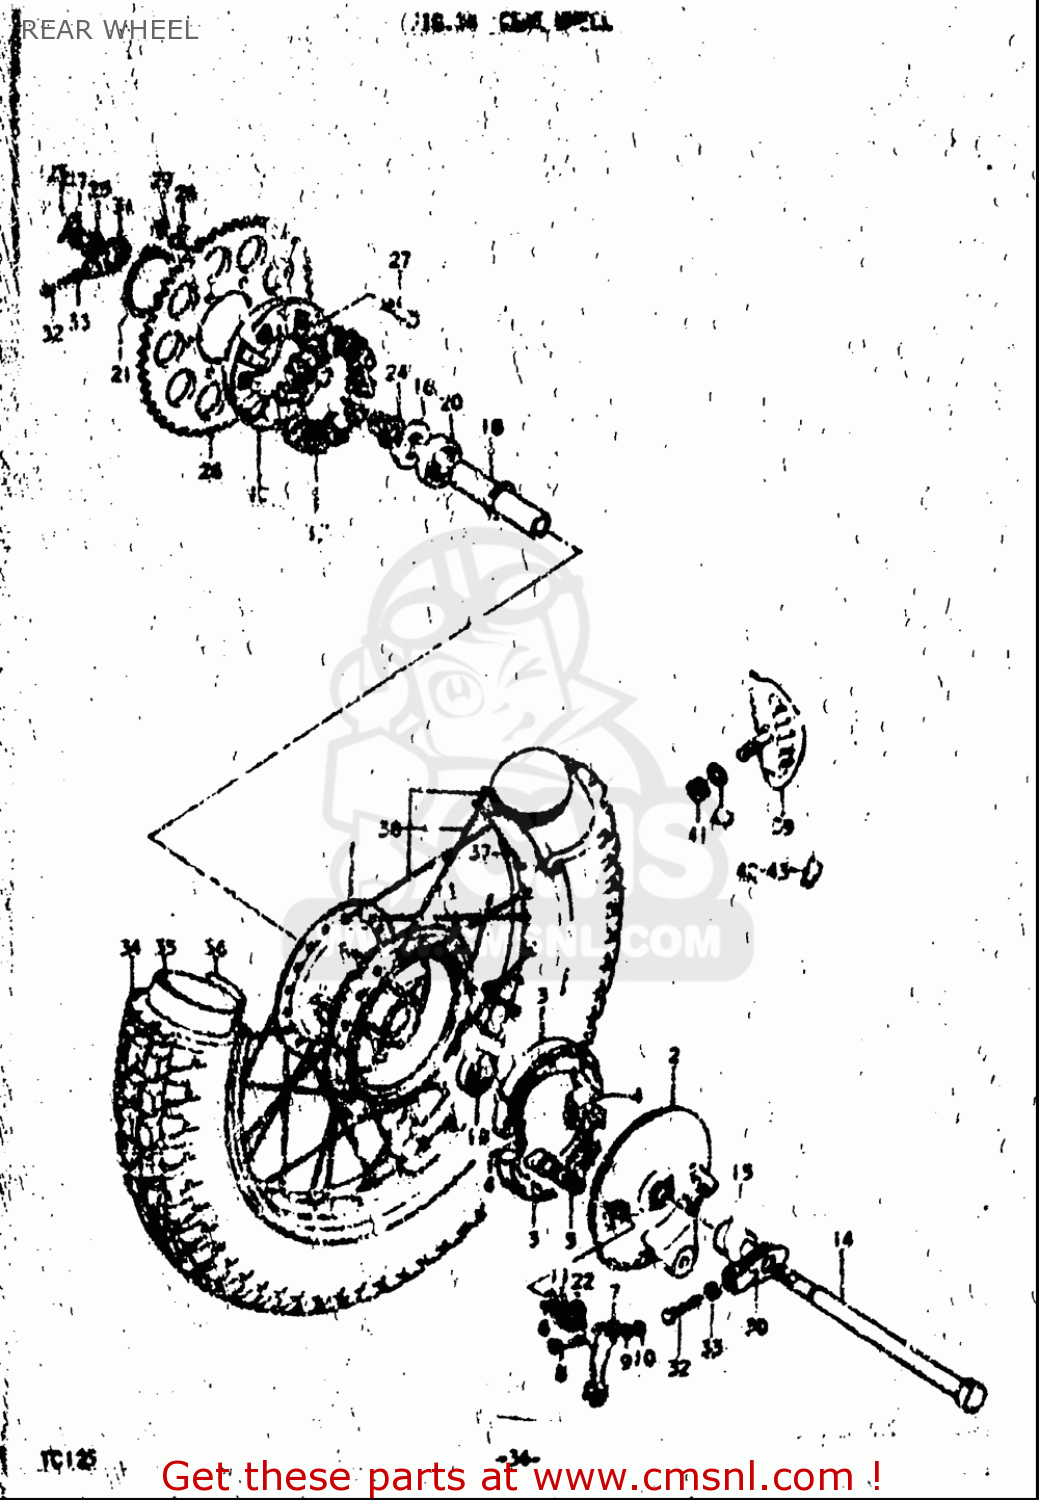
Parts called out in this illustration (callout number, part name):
3	SHOE SET,BRAKE (NAS)
4	SPRING(L:35.8)
5	CAM,FR BRAKE
6	O RING(D:2.5,ID:11.4)
8	BOLT(6X31)
9	WASHER
10	NUT
11	WASHER(12.5X20X1)
13	ABSORBER,RR WHEEL HUB SHOCK
14	AXLE,REAR
15	SPACER(15.2X22X26)
16	SPACER,RR AXLE,L
17	NUT 12MM
19	BEARING
20	B1 15X42X13 BEA
21	CIRCLIP
22	SPRING
23	PIN
24	SPACER,CHAIN ADJUSTER,L
25	NUT
27	BOLT(8X32)
28	WASHER
30	ADJUSTER,CHAIN
31	ADJUSTER,CHAIN,L
32	BOLT(8X40)
33	NUT
35	TUBE ASSY,INNER
36	PROTECTOR,INNER TUBE
38	SPOKE SET
39	STOPPER,BEAD
40	WASHER
41	NUT
42	BALANCER,WHEEL (30G)
43	BALANCER,WHEEL (50G)
